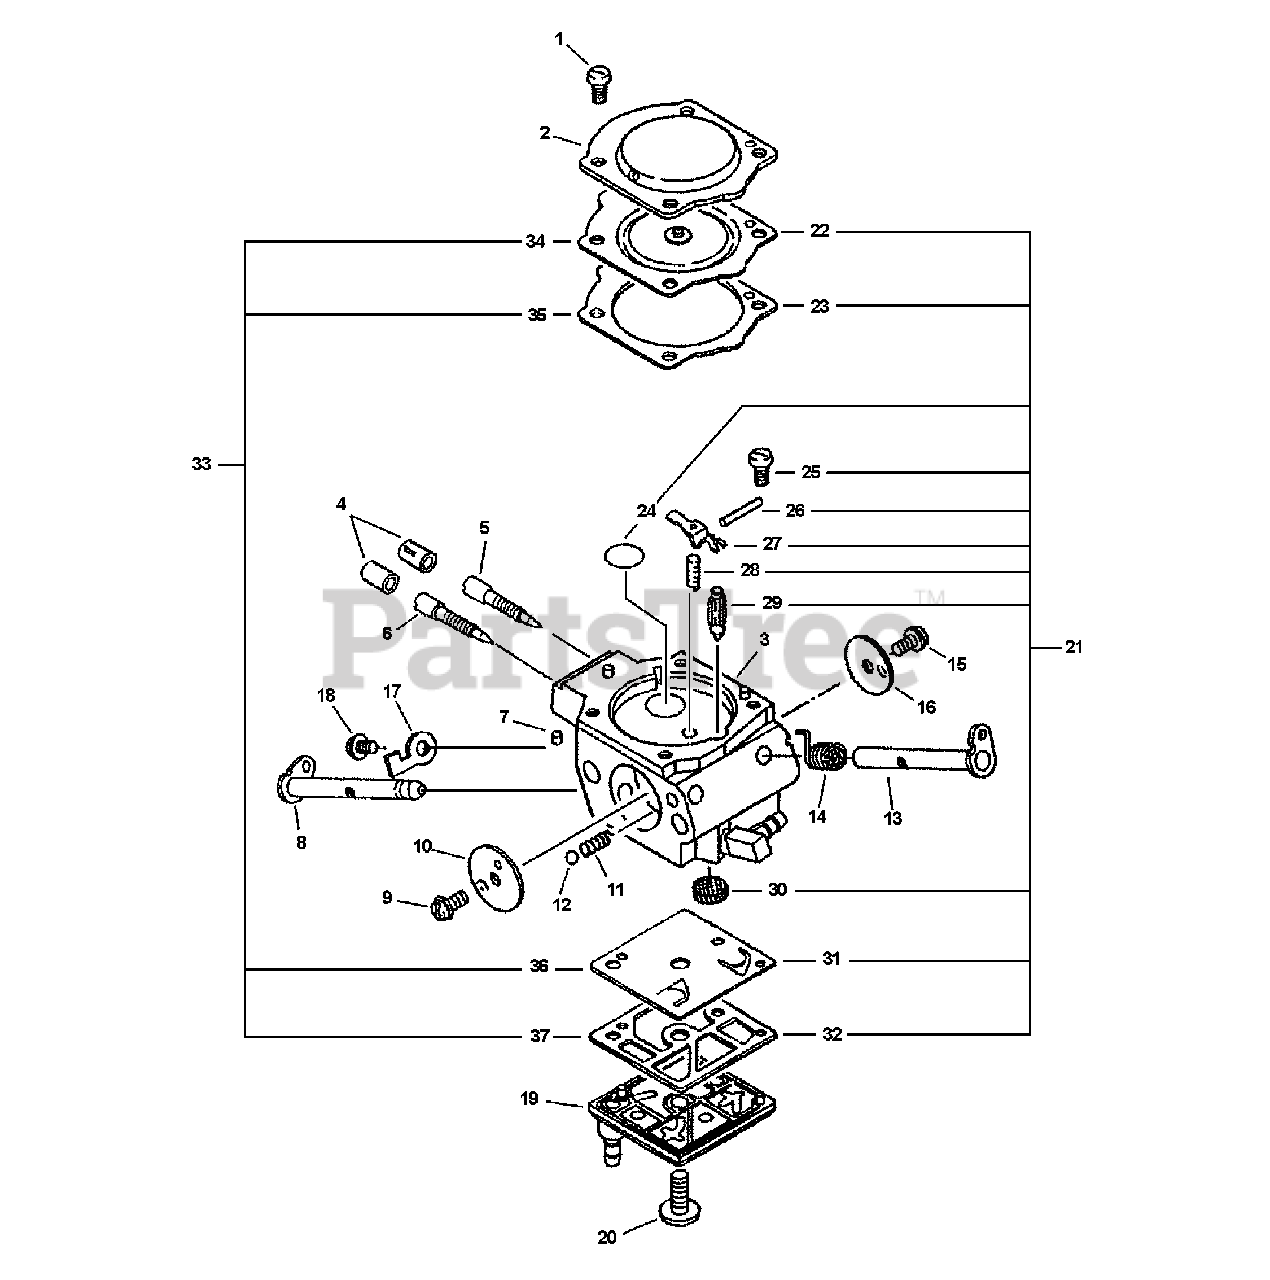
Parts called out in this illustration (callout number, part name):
1	SCREW
2	COVER, METERING DIAPHRAGM
3	BODY, CARBURETOR
4	CAP, LIMITER
5	NEEDLE, LOW SPEED
6	NEEDLE, HIGH SPEED
7	PLUG, FRICTION
8	SHAFT, CHOKE
10	VALVE, CHOKE
11	SPRING, CHOKE FRICTION
12	BALL, CHOKE FRICTION
13	SHAFT, THROTTLE
14	SPRING, THROTTLE RETURN
16	VALVE, THROTTLE
17	STOP, THROTTLE
19	COVER, FUEL PUMP
20	SCREW, PUMP COVER
21	REPAIR KIT
22	DIAPHRAGM, METERING
23	GASKET, METERING DIAPHRAGM
24	PLUG, WELCH
25	SCREW, METERING LEVER PIN
26	PIN, METERING LEVER
27	LEVER, METERING
28	SPRING, METERING LEVER
29	VALVE, INLET NEEDLE
30	SCREEN, INLET
31	DIAPHRAGM, FUEL PUMP
32	GASKET, FUEL PUMP
33	DIAPHRAGM/GASKET KIT
34	GASKET, METERING DIAPHRAGM
35	DIAPHRAGM, METERING
36	DIAPHRAGM, FUEL PUMP
37	GASKET, FUEL PUMP
